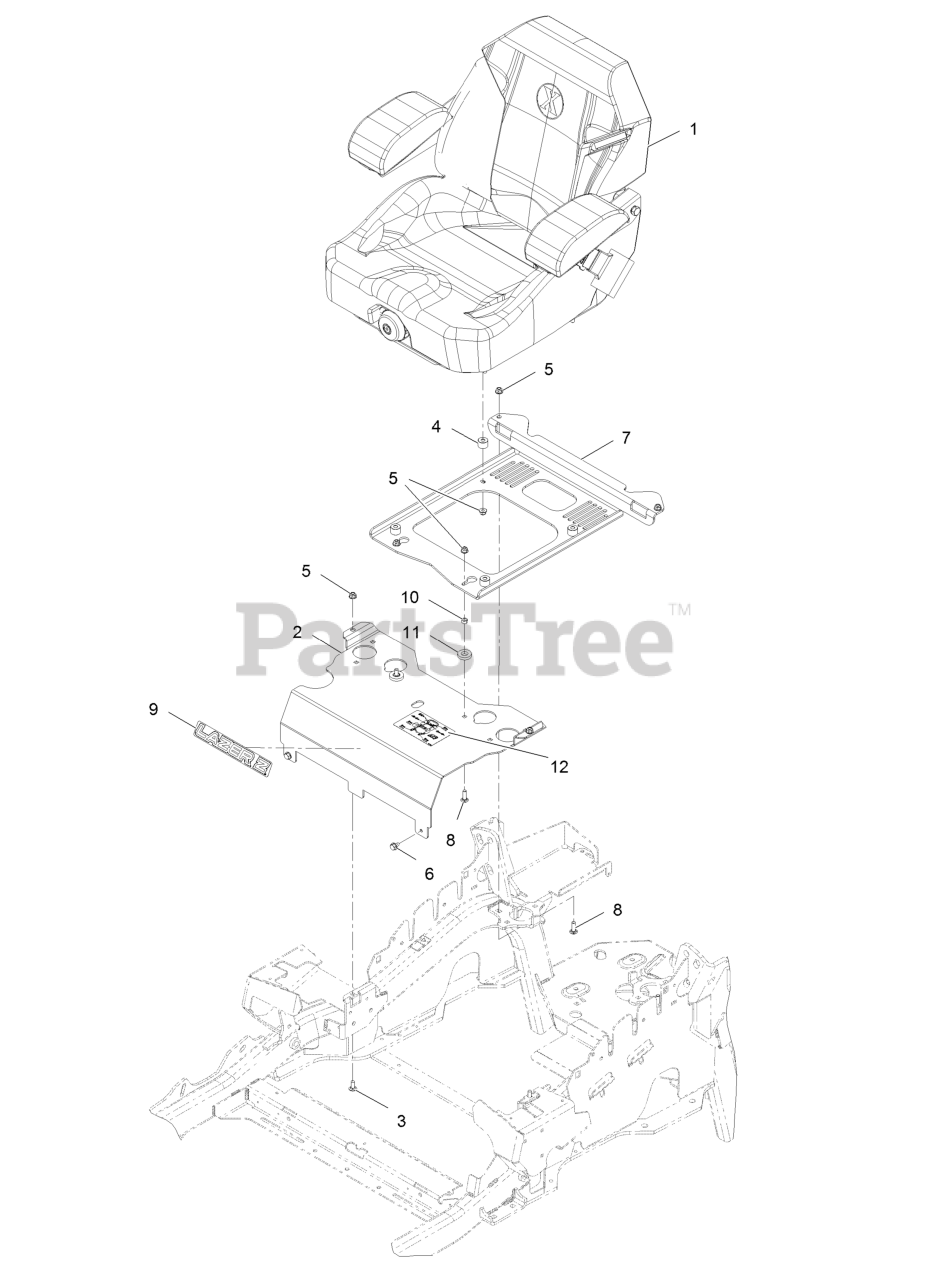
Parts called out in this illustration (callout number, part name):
1	Kit-Suspension Seat
2	Panel-Front, Seat Mount
3	Bolt-Carriage 5/16-18 X 3/4 Short Neck
5	Nut-Nyloc 5/16-18 Flg
6	Screw-HWH 5/16 X 1/2 Tf
7	Plate-Support, Seat
8	Bolt-Carriage 5/16-18 X 1 Sp
9	Decal, Lazer Model
10	Nut-Hex 5/16-18
11	Spacer-Blade Drive
12	Decal-Service Aid
